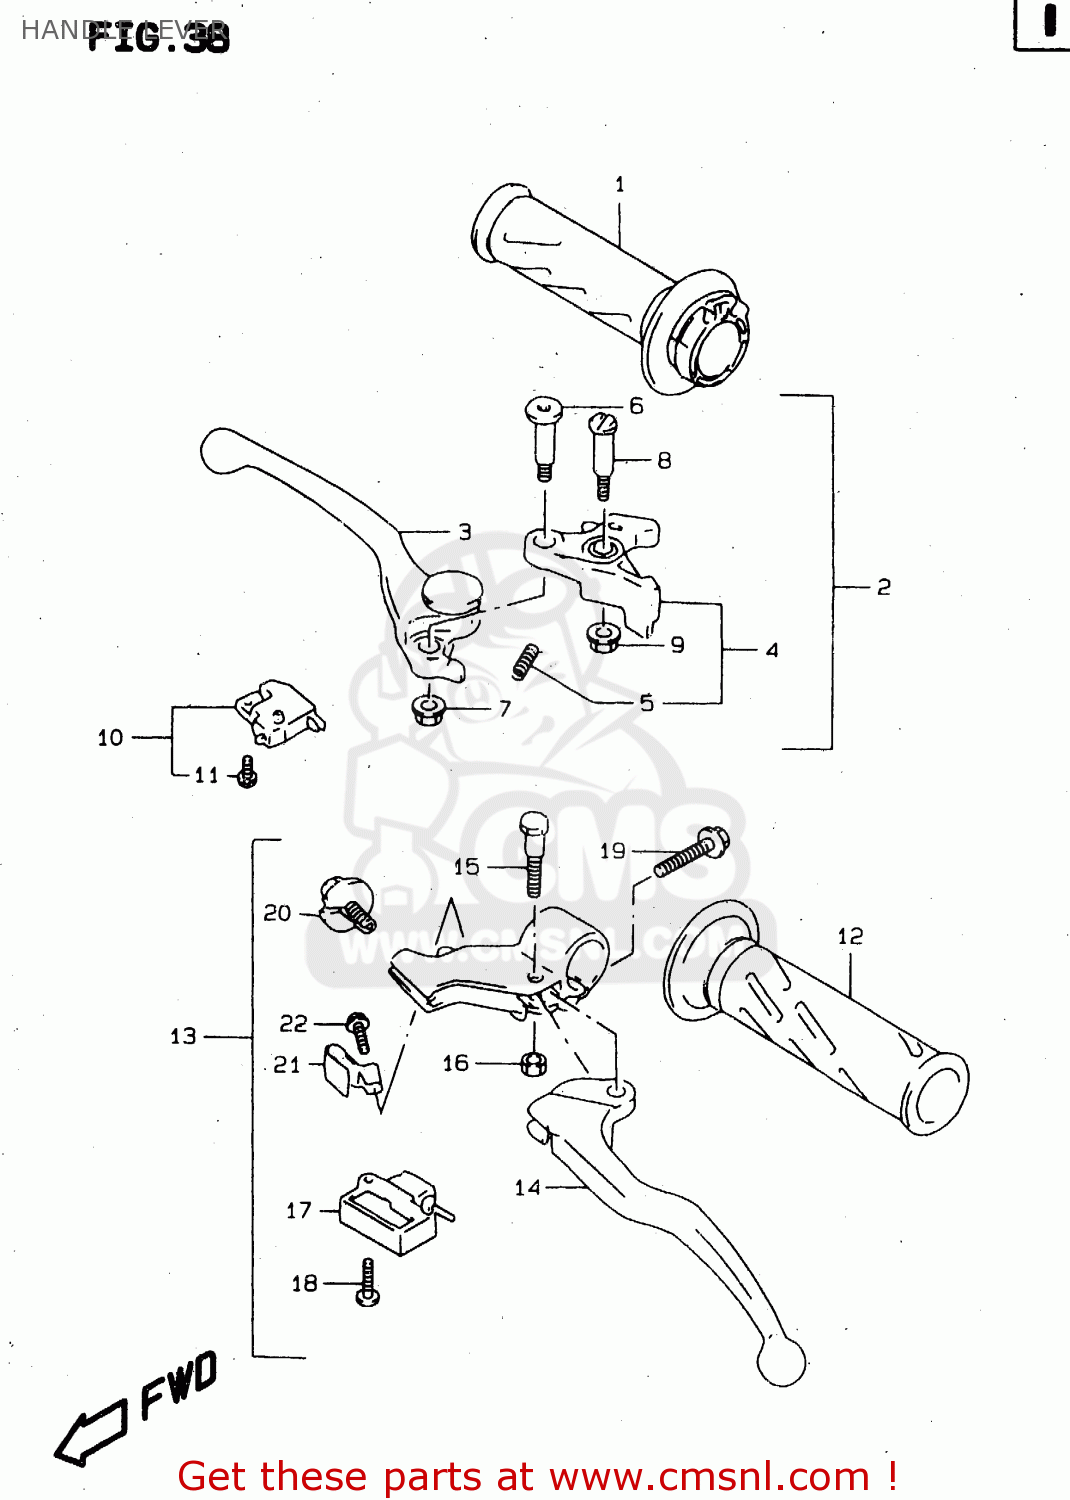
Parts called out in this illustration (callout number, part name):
1	GRIP,THROTTLE
2	LEVER ASSY,BRAKE
3	LEVER,ADJUST
4	KNOCKER
5	SPRING
6	BOLT,LEVER
7	NUT
8	BOLT,LEVER PIVOT
9	NUT
10	SWITCH ASSEMBLY,STOP
11	SCREW
12	GRIP,LEFT
13	LEVER ASSEMBLY,CLUTCH
14	LEVER,CLUTCH
15	BOLT,LEVER SET
16	NUT
17	SWITCH,CLUTCH
18	SCREW
19	SCREW
20	NUT,CABLE ADJUSTER
21	SPRING,ADJUST
22	SCREW,SPRING
